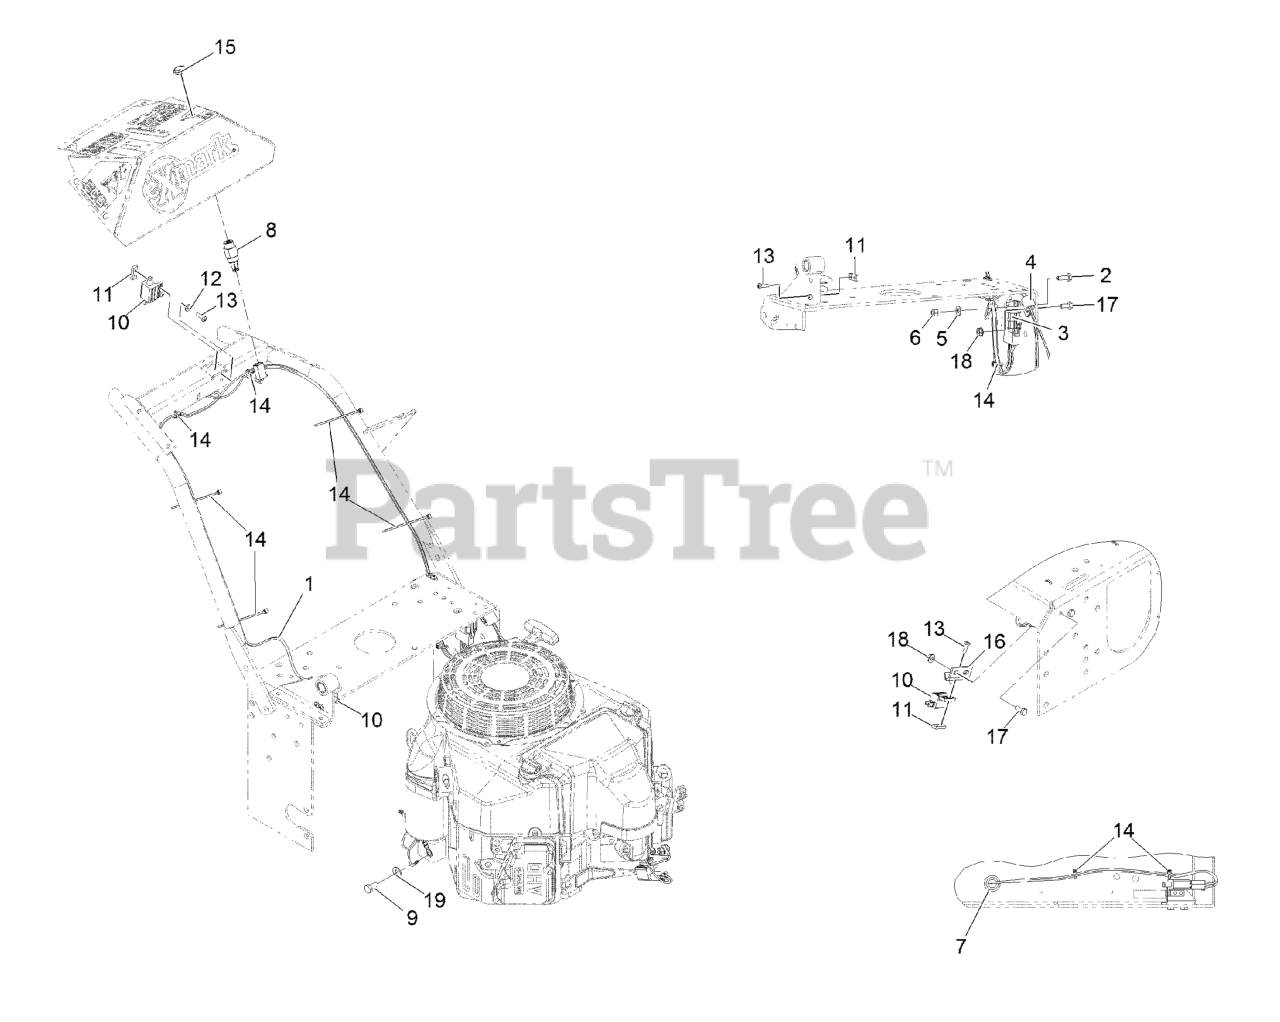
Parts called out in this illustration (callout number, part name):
1	HARNESS-WIRING
2	SCREW-HH
3	MODULE-INTERLOCK
4	CLIP-LOOM
5	WASHER-FLAT
6	NUT-LOCK, NI
7	GROMMET
8	SWITCH & KEY (INCLUDES NU
9	SCREW-HH
10	SWITCH-OPEN, NORMALLY
11	PLATE-TAPPED
12	WASHER-FLAT
13	SCREW-PPH
14	TIE-CABLE
15	NUT-SWITCH, IGNITION
16	BRACKET-SWITCH, BLADE
17	SCREW-HH
19	WASHER-PLAIN
